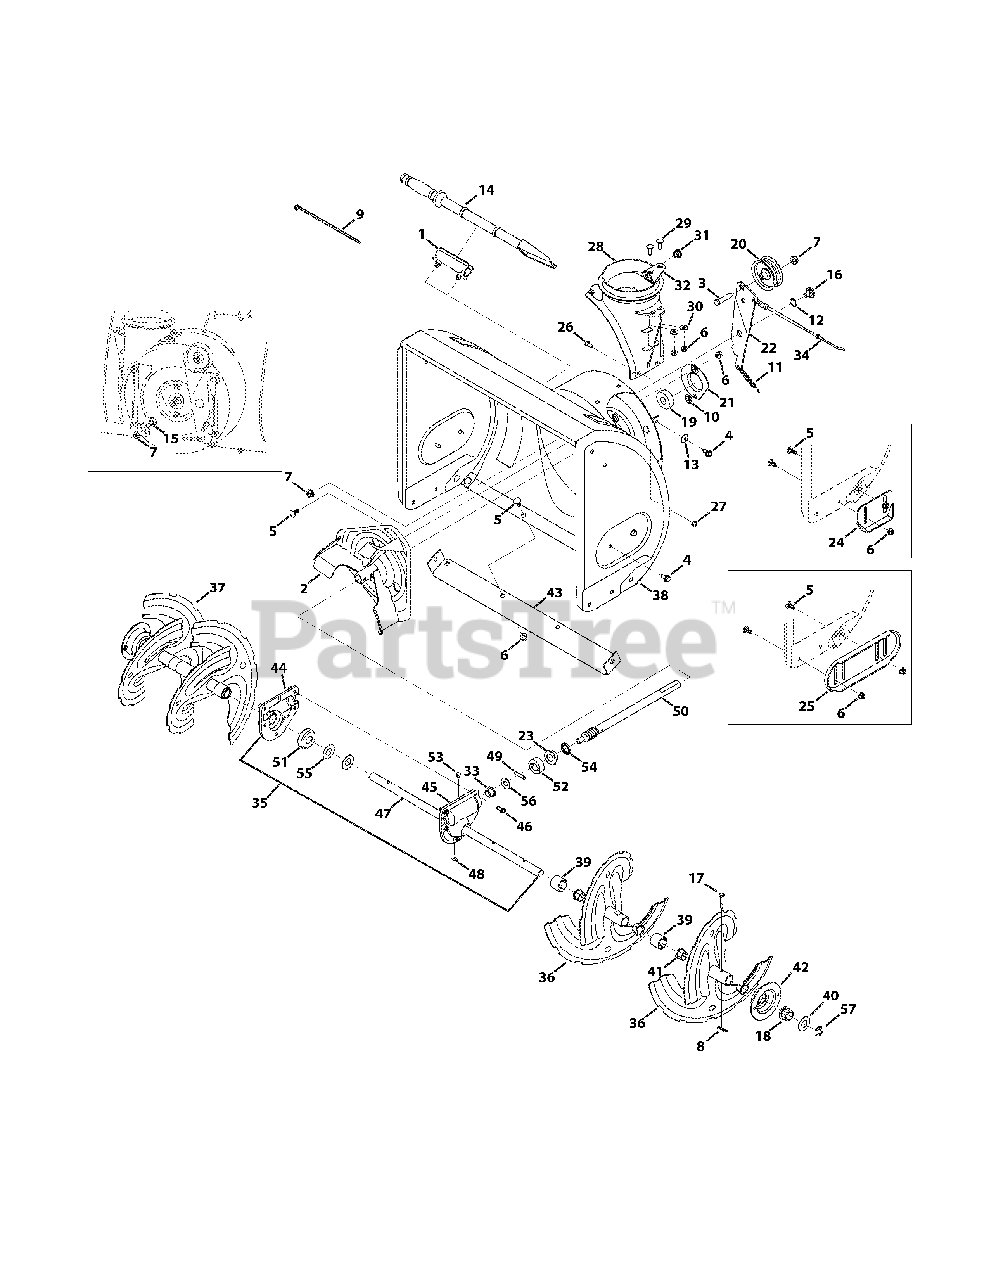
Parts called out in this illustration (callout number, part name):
1	Cleanout Tool Mount
2	Impeller Assembly, 12"
3	Hex Screw, 3/8-16 x 1.75
4	Hex Washer Screw, 5/16-18 x .750
5	Carriage Bolt, 5/16-18 x .750
6	Flange Lock Nut, 5/16-18
7	Flange Lock Nut, 3/8-16
8	Bow-Tie Cotter Pin
9	Cable Tie, 3/16 x .05 x 7.4
10	Push Nut, .25 Dia.
11	Extension Spring
12	Wave Washer, .625 x .885 x .015
13	Bell Washer, .340 x .872 x .060
14	Chute Cleanout Tool
15	Shoulder Bolt, .496 x .336 x 3/8-16
16	Shoulder Screw, .625 x .17 x 3/8-16
17	Shear Pin, .25 x 1.50
18	Hex Flange Bearing
19	Ball Bearing, .75 ID x 1.85 OD
20	Idler Pulley, 2.75 OD
21	Bearing Housing, 1.85 ID
22	Auger Idler Bracket
23	Flange Bearing, .75 ID x 1.0 OD x .59
25	Deluxe Skid Shoe
26	Carriage Screw, 1/4-20 x .75
27	Flange Lock Nut, 1/4-20
28	Chute Adapter, 5"
29	Carriage Screw, 5/16-18 x 1.00
30	Flat Washer, .349 x .879 x .063
31	Plastic Bushing, .380 ID
32	Chute Crank Bracket
33	Flange Bearing, .50 ID x .75 OD x .59
34	Auger Drive Cable
35	Gearbox Assembly, 26"
36	Spiral Assembly, LH
37	Spiral Assembly, RH
38	Auger Housing Assembly, 26"
39	Spacer, 1.2500 x .75 ID x 1.00
40	Flat Washer, .76 x 1.49 x .06
41	Flange Bushing, .800 ID x .910 OD
42	Hex Bearing Housing
43	Shave Plate, 26"
44	Housing Assembly, RH
45	Housing Assembly, LH
46	Hex Washer Screw, 1/4-20 x .750
47	Auger Axle, 26"
48	Hi-Pro Key
49	Dowel Pin, .25 OD x 1.25 LG
50	Worm Shaft, .75 OD
51	Worm Gear 20 T
52	Thrust Collar, .756 ID x .600
53	Plug, 1/4 x .437
54	Oil Seal, .75 x 1.131 x .188
55	Flat Washer, .760 ID x 1.50 ID
56	Flat Washer, .51 x 1.12 x .06
57	E-Ring, .750
